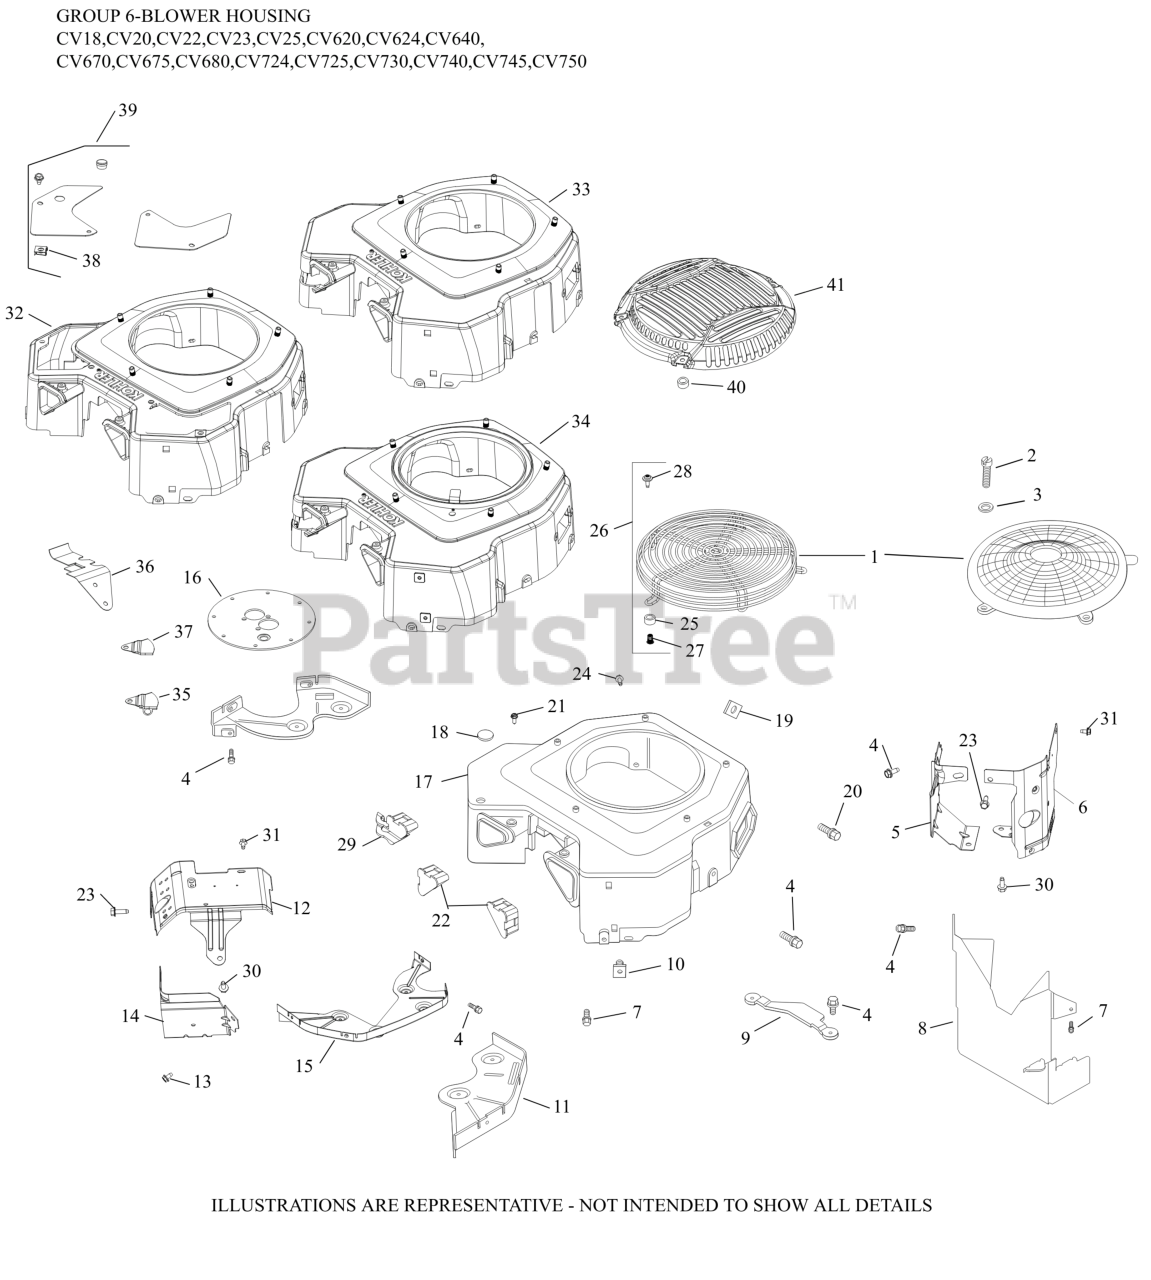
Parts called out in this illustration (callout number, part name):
5	BAFFLE, VALLEY #1 CYLINDER
6	BAFFLE, LEFT BARREL
12	KIT, CYL BAFFEL #1 SIDE
14	BAFFLE, VALLEY #2 CYLINDER
15	KIT, BACKING PLATE
17	HOUSING, BLOWER
20	SCREW, THREAD FORMING
22	COVER, BLOWER HOUSING-USE 24 096 160-S
24	SCREW, THREAD FORMING
27	INSERT, THREADED (M5)
28	SCREW, SEMS
30	SCREW, THREAD FORMING
31	SCREW, THREAD FORMING
38	CLIP, BAFFLE MOUNTING
39	KIT, ACCESS PANEL
41	GUARD, GRASS SCREEN (METAL)
NI	SCREW, THREAD FORMING
